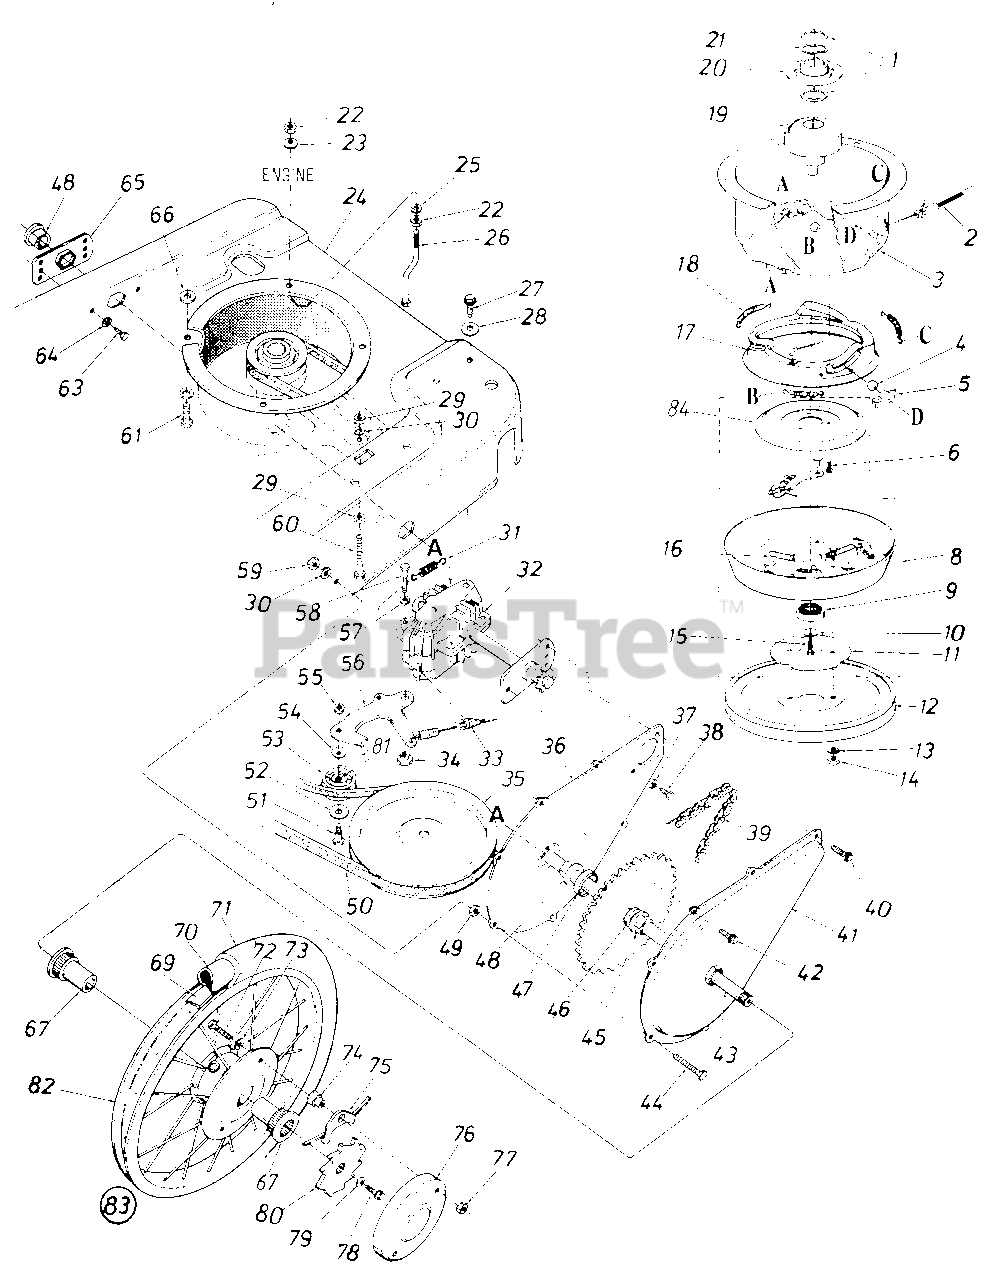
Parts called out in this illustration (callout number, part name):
1	WASHER-SERRATED
2	CABLE-CLUTCH
3	HOUSING-CLUTCH
4	BALL-STEEL
5	BALL-BLOCK
6	SCREW-HEX WASH SF TAPP
8	HOUSING-CLUTCH MBC
9	BEARING-BALL
10	WASHER-BELL
11	HOUSING ASSY-W/FPA
12	PULLEY-5/8-V
13	WASHER-LOCK-3/8
14	NUT-HEX 3/8-24
15	SCREW-HEX 7/16 N.F. x 2 GR.5
16	SPRING-COMPRESSION
17	CONE-BRAKE CUP
18	SPRING-EXTENSION
19	ADAPTER-FIXED PULLEY
20	PULLEY-MOVABLE
21	WASHER-WAVE
22	NUT-HEX 5/16-18
23	WASHER-BELL .337 x .867 x .057
24	FRAME-HI WHEEL
25	WASHER-LOCK-5/16
26	GUARD-BELT-5/16 BOLT
27	SCREW-HEX WASH HD 5/16-18X1/2
28	WASHER-BELL .3/8ID x 1.12OD x .030
29	NUT-HEX 1/4-20
30	LOCK WASHER 1/4 DIA
31	SPRING-EXTENSION
32	TRANSMISSION-COMP
33	CABLE-CLUTCH x 50.0
34	SPACER-SHLD
35	PULLEY
36	COVER-CHAIN-45T
37	LOCK WASHER 1/4 DIA
38	SCREW-HEX B-TAP 1/4 x .38
39	#48 CHAIN 1/2 PITCH x 51 LINKS
40	SCREW-HEX WASH SF TAPP
41	CASE-CHAIN-45T
42	SCREW-HEX B-TAP 1/4 x .38
43	AXLE ASSY-RR
44	SCREW-HEX 1/4-28 x .88
45	BEARING-HEX FLANGE
46	WASHER-FL-.640 ID x .94 OD
47	SPACER-.630 x 1.250 OD
48	BEARING-HEX FLANGE
49	NUT-HEX JAM 1/4-28
50	BELT-V- 3/8 x 28
51	SCREW-SHLD
52	WASHER-FL .995 x .032
53	KIT-PULLEY
54	WASHER-SPRING BELL
55	NUT-HEX 1/4-28
56	BRACKET ASSY-IDLER
57	WASHER-FL
57	LOCK WASHER 1/4 DIA
58	SCREW-HEX 1/4-20 x 1.25
59	NUT-HEX 1/4-28
60	SCREW-HEX 1/4-20 x 2.00
61	SCREW-HEX R
63	SCREW-HEX B-TAP 1/4 x .38
64	LOCK WASHER 1/4 DIA
65	BEARING-CUP HEX
66	WASHER-FL-.406 ID x .74 OD x .063
67	BEARING-FLANGE
69	RIM STRIP
70	TUBE-16 x 2.12
71	TIRE-16 x 2.125
72	SCREW-HEX 5/16-18 x 1.00
73	WASHER-INTERN L 5/16
74	NUT-HEX 5/16-18 SPEC
76	COVER-WHEEL
77	NUT-HEX 5/16-18
78	SCREW-TAP
79	WASHER-SPRING BELL
80	RACHET-WHEEL
81	BEARING-NEEDLE
82	WHEEL RIM 16.0 x 2.1
83	WHEEL ASSY W/TIRE 16 x 2.12
84	CONE-CLUTCH
